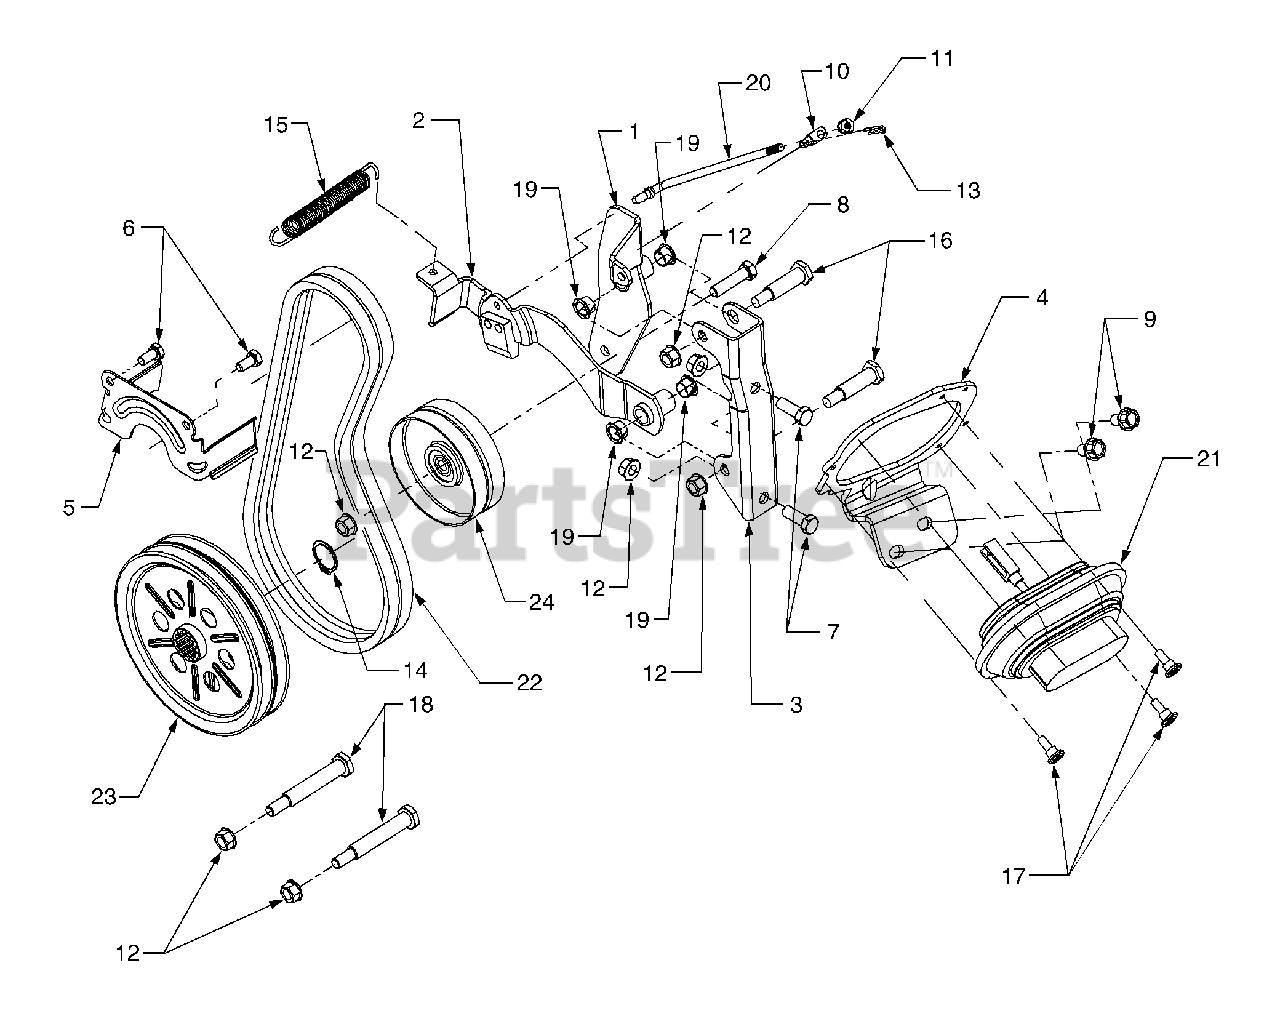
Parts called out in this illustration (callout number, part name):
1	Bracket, Idler
2	Bracket Assembly, Brake
3	Bracket, PTO Mounting
4	Bracket, Actuator
6	Screw, Hex Cap 5/16-24 x .625 GR5
7	Screw, Hex Cap 3/8-16 x 1.0 GR5
8	Screw, Hex Cap 3/8-16 x 1.5 GR5
9	Screw, Hex Wash. Hd. Tapp 3/8-16 x .75
10	Ferrule, Brake Adjustment
11	Nut, Hex Insert Lock, 1/4-20
12	Nut, Flange Lock, 3/8-16
13	Pin, Internal Cotter
14	Snap Ring, 1.0 Dia Shaft
15	Spring, Extension, .530 x 4.74
16	Shoulder Screw, .498 x 1.45
17	Shoulder Screw, .375 x .28
18	Shoulder Screw
19	Bearing, Nylon Flange
20	Rod, PTO Brake
21	Vacuum Actuator
22	V-Belt, A-Section x 37.63
23	Pulley, PTO Drive. 6.75-Double
24	Pulley, Flat Idler, 4.0
